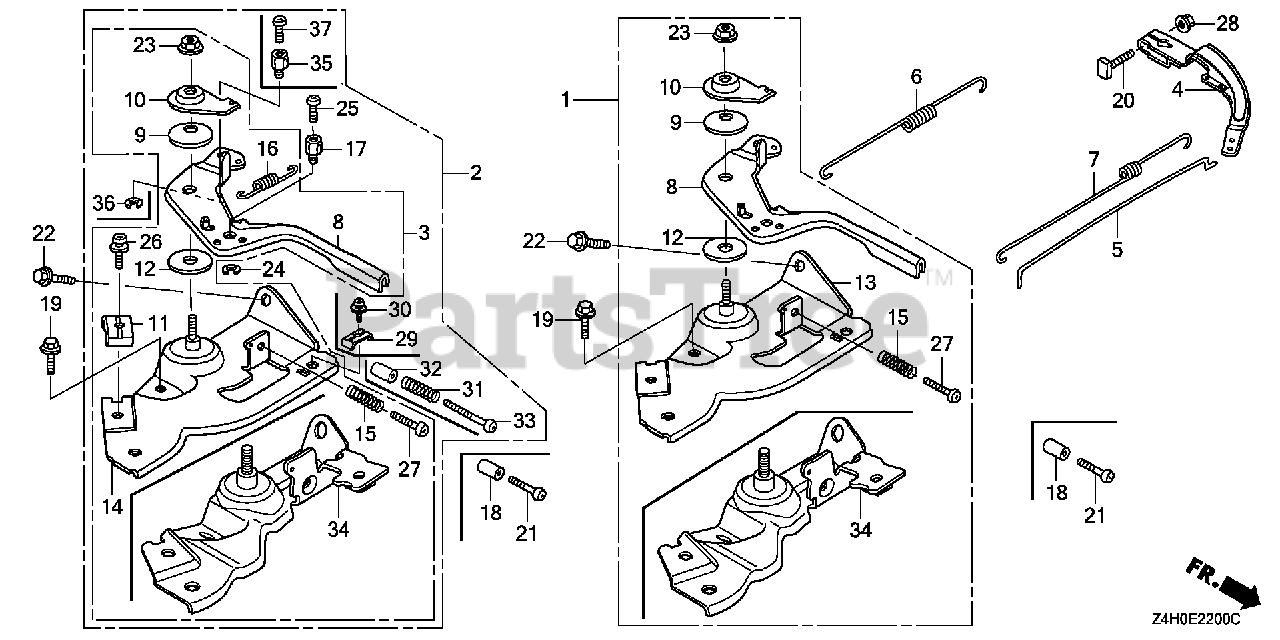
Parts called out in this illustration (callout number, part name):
3	CONTROL ASSY. (REMOTE)
4	ARM, GOVERNOR
5	ROD, GOVERNOR
6	SPRING, GOVERNOR
7	SPRING, THROTTLE RETURN
8	LEVER, CONTROL
9	SPRING, LEVER
10	WASHER, CONTROL LEVER
11	HOLDER, CABLE
12	SPACER, CONTROL LEVER
14	BASE, CONTROL
15	SPRING, CONTROL ADJUSTING Use from Engine SN 2327377.
16	SPRING, CABLE RETURN
19	BOLT, FLANGE (6X12) (CT200)
20	BOLT, GOVERNOR ARM
22	BOLT, FLANGE (6X20) (CT200)
23	NUT, SELF-LOCK (6MM)
26	SCREW, PAN (5X16)
27	SCREW, PAN (5X25)
28	NUT, FLANGE (6MM)
